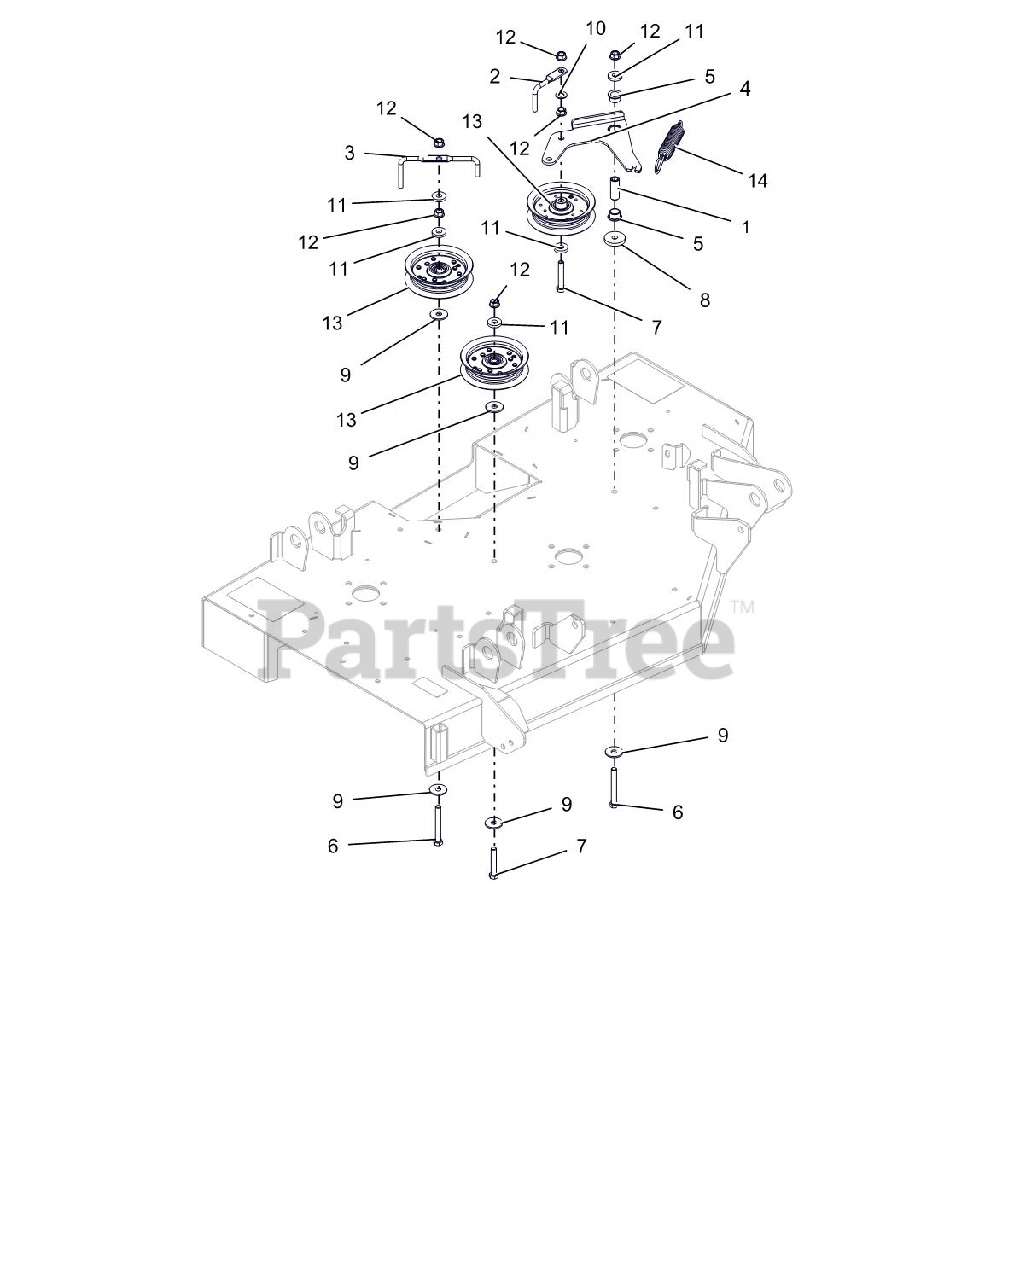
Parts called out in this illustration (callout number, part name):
1	SPACER, .375IDX.625ODX1.66 PM
2	WIREFORM, BELT FINGER
3	BELT FINGER
4	WLDMT, IDLER ARM-42"
5	BSHG-FLG, .625X.750X.500X1.00
6	BLT-HEX .38-16X3.00 GR5 FTH YZ
7	@BLT-HEX .38-16X2.25 GR5 YWZC
8	WSHR,FLT STL.406X1.50X.245YWZC
9	@WSHR-FL-STL .406X1.25X.10 ZC
10	@WSHR-FL-STL.406X.812X.065 YWZ
11	WSHR-FL-STL .406X1.00X.188 YWZ
12	@NUT-LK-TOP-FLG .38-16 YWZC
13	ASM, IDLER 4"
14	SG-TENS .135X.98X6.0 WLD 62
